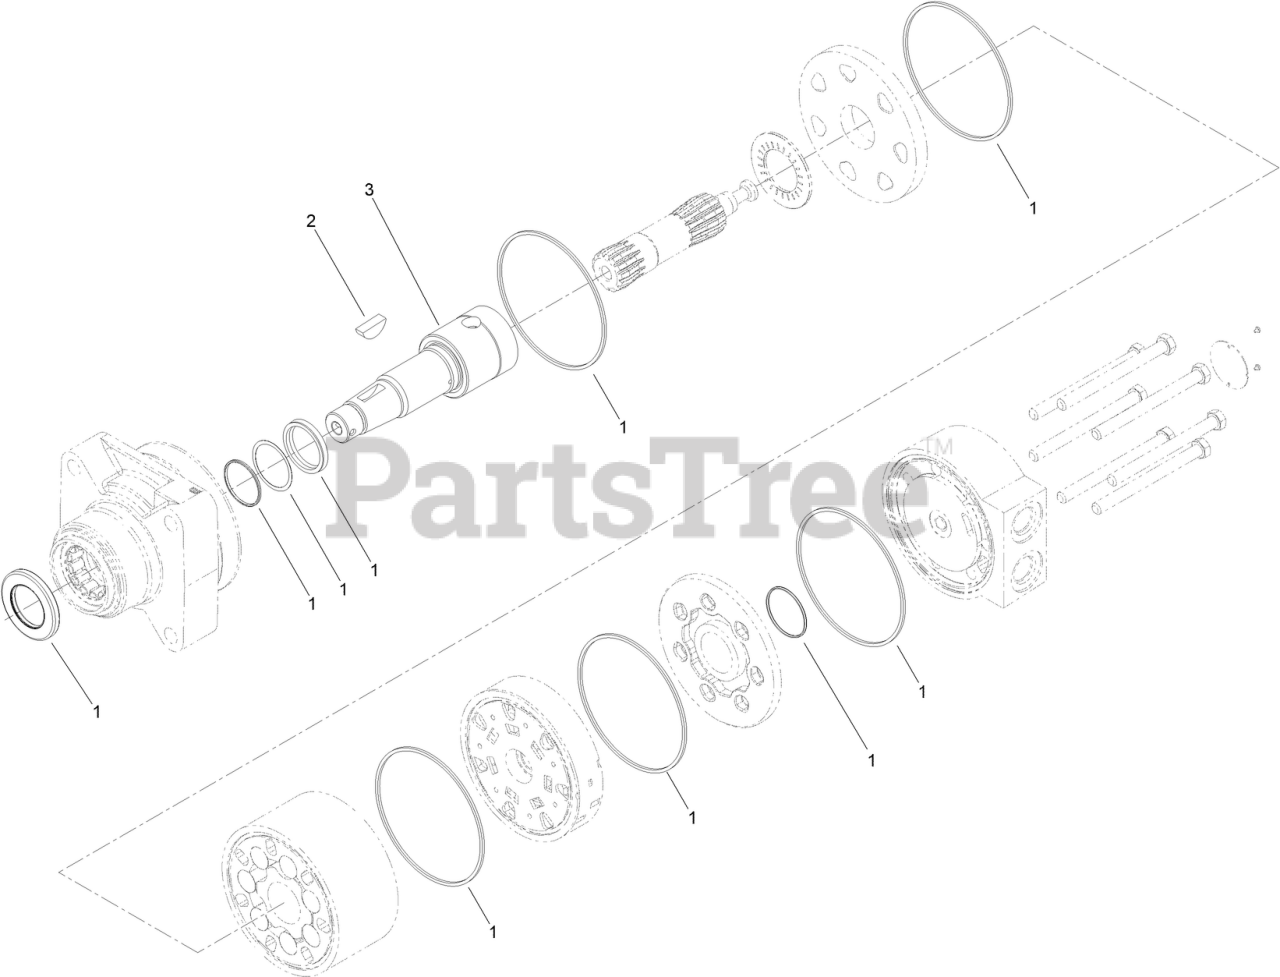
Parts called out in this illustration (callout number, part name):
1	SEAL KIT
2	KEY-WOODRUFF
3	SHAFT - COUPLING TGK
